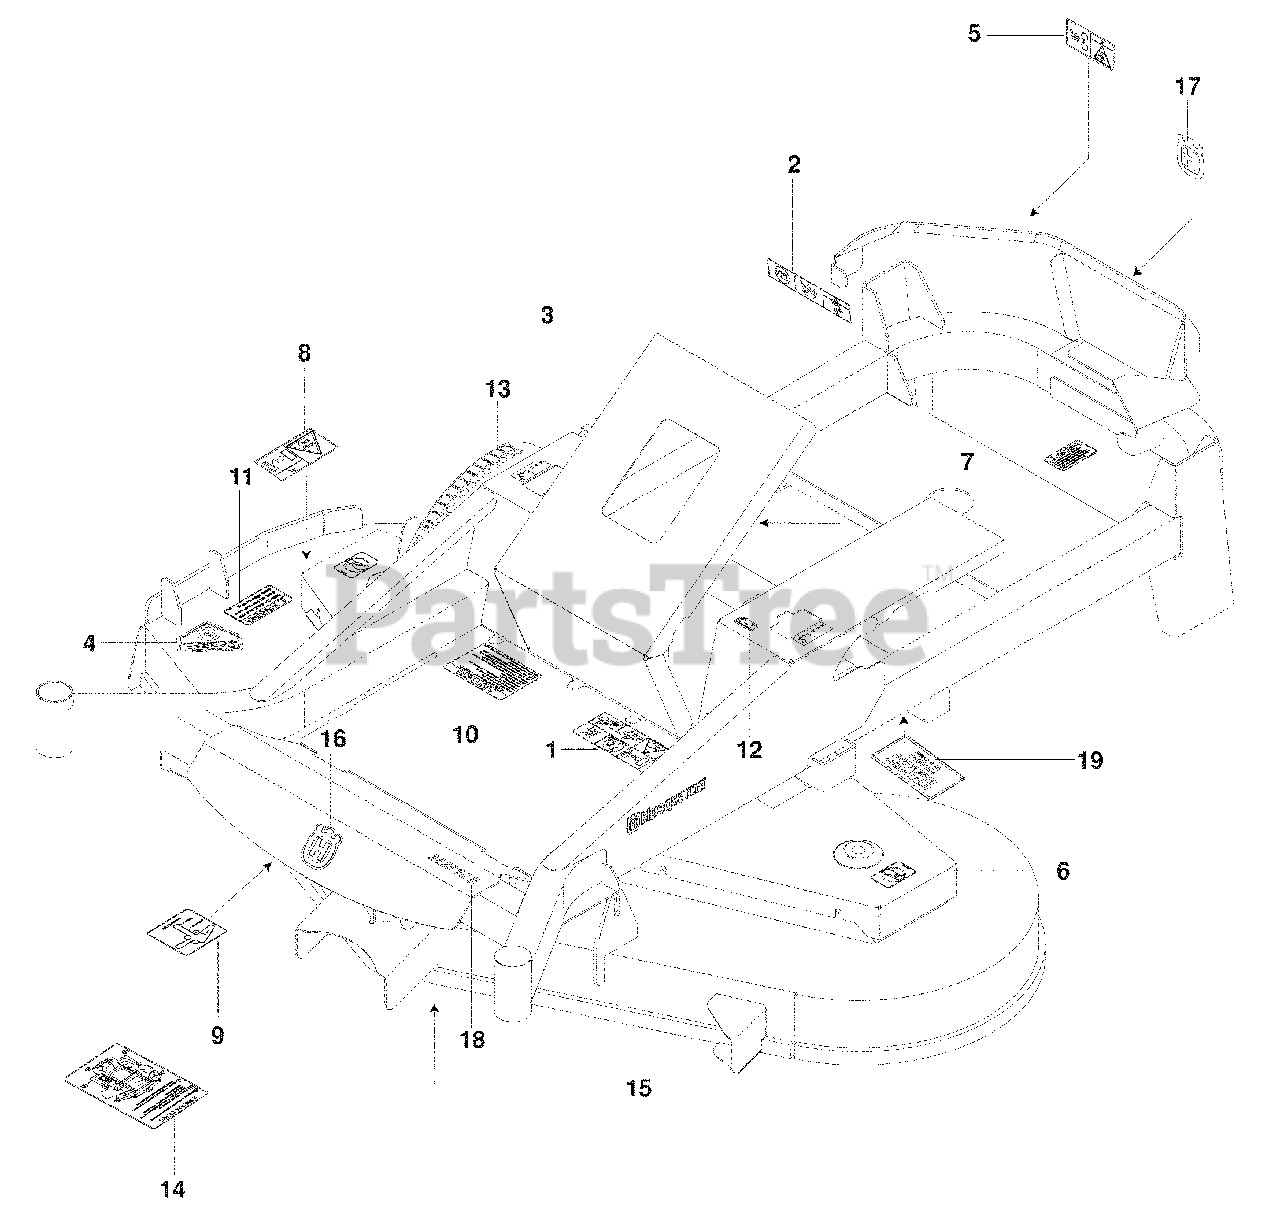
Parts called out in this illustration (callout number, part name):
1	DECAL, WARNING
2	DECAL, BATTERY WARNING
3	DECAL, MOTION CONTROL
4	DECAL, CPSC
5	DECAL, DANGER BLT DRIVE
6	DECAL, NO STEP
7	DECAL, PROP 65
8	DECAL, SEVERING
9	DECAL, BELT ROUTING
10	DECAL, WARNING
11	DECAL, WARNING
12	DECAL, F.S.T
13	DECAL, HEIGHT ADJUST
14	DECAL, SERVICE
15	DECAL, HUSQVARNA
16	DECAL, CROWN H
17	DECAL, CROWN H
18	DECAL, M6128
19	DECAL, HYDROGEAR
